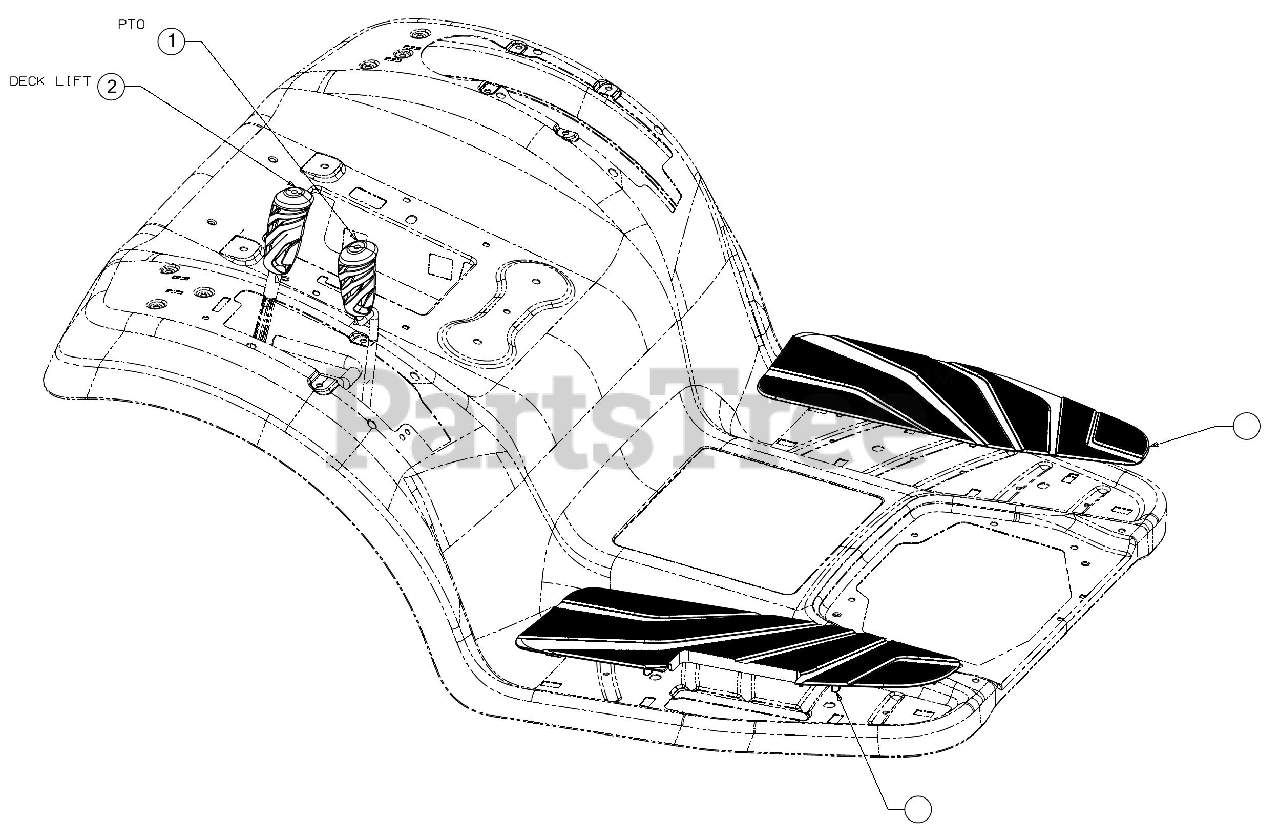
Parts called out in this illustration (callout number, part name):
1	PTO HANDLE GRIP .355 ID
2	LIFT HANDLE GRIP .542 ID
4	FOOTPAD-LEFT
5	FOOTPAD-RIGHT
